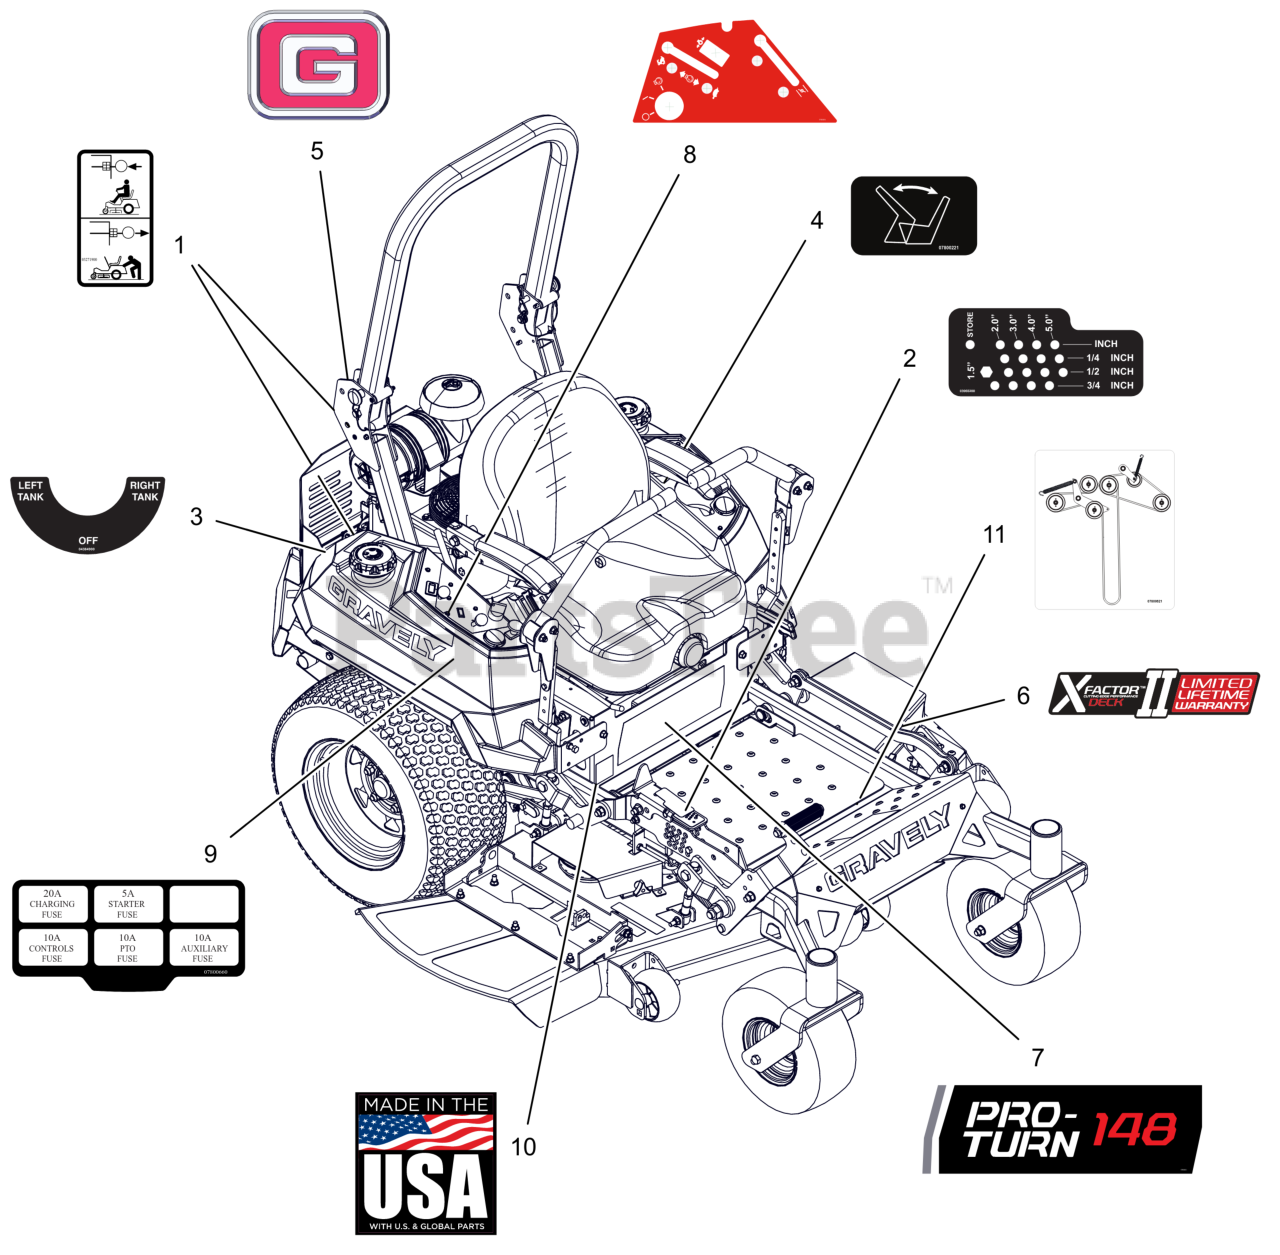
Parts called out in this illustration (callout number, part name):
1	DECAL, TRANSMISSION DISCONNECT
2	DECAL, HEIGHT OF CUT
3	DECAL, FUEL VALVE
4	DECAL - SEAT RELEASE
5	DECAL, GRAVELY BRAND
6	DECAL, X-FACTOR DECK
7	DECAL, PRO-TURN 148
8	DECAL, NON-EFI CONTROL PANEL
9	DECAL, FUSE BLOCK
10	DECAL, MADE IN USA
11	DCL,BELT ROUTE-RH V-SIDE IDLER
